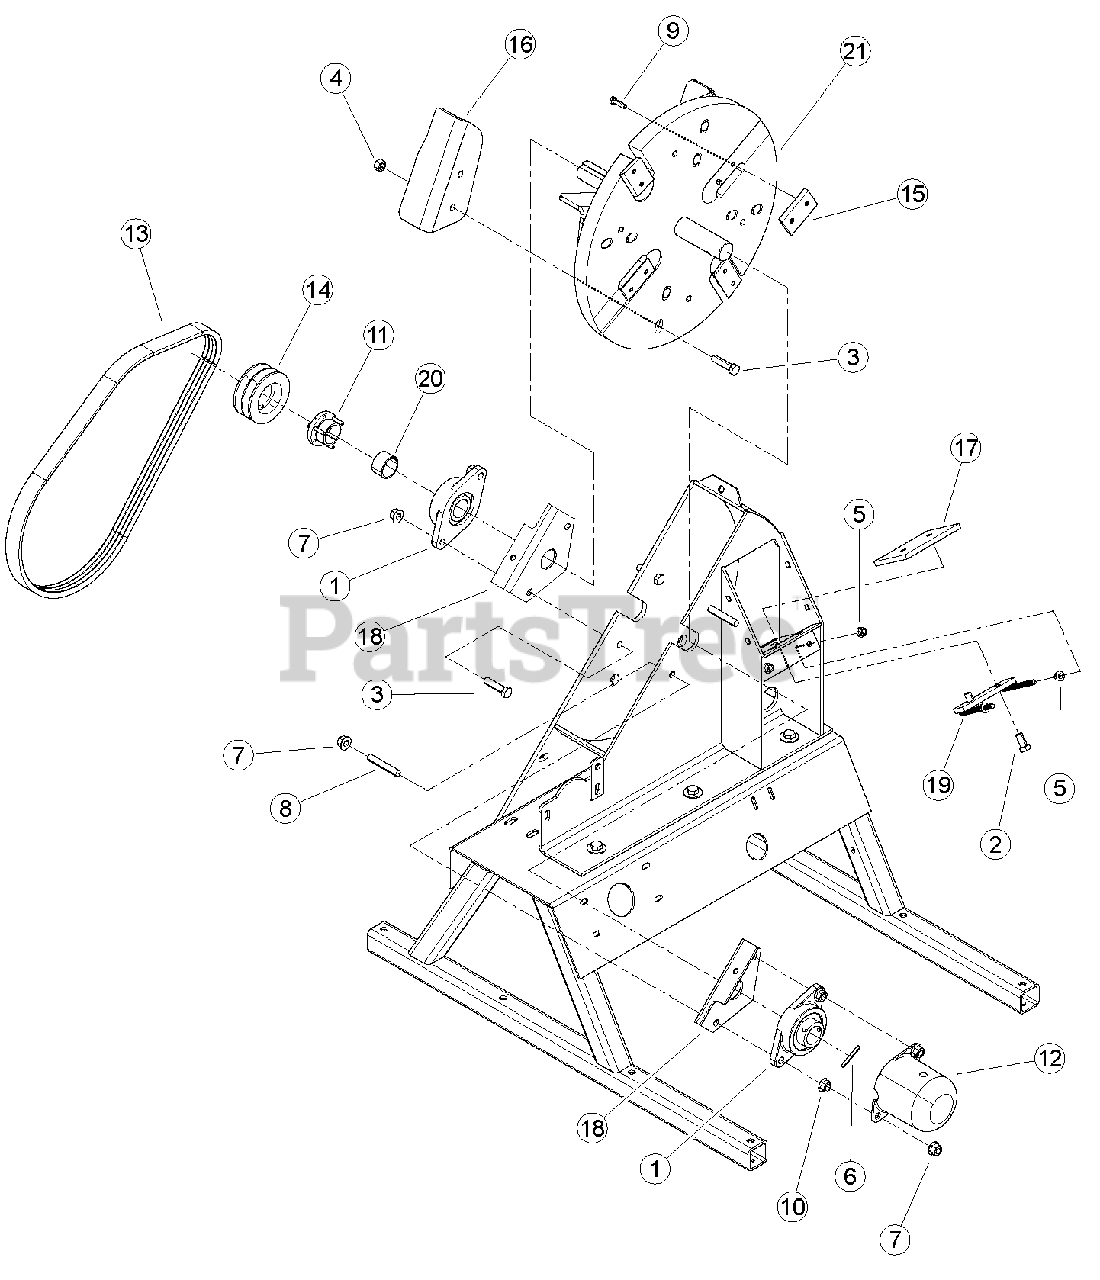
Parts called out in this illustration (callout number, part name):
1	BEARING, 1-1/2" 2-BOLT SET SCREW
2	BOLT, 1/2 X 1 GR5 HEX CAPSCREW ZP
3	BOLT, 1/2 X 2 GR5 HEX CAPSCREW ZP
4	NUT, 1/2" CENTERLOCK GRB ZP
5	NUT, 3/8" SERRATED FLANGE NC ZP
6	SPRINGPIN, 1/4 X 2" LG
7	NUT, 1/2-13 NYLOCK FLANGE
8	STUD, 1/2"-13 X 3"LG B7 ZP
9	BOLT, 5/16 X 1-1/4 HHD GR8 PATCH
10	NUT, 1/2 SPIRAL LOCK NC ZP
11	BUSHING, SH 1-1/2"
12	CAP, LARGE SHAFT
13	BELT, 2RBX56
14	SHEAVE, 2B 3.8 SH
15	BLADE, TWO EDGE TOOL STEEL (FOR SERVICE ORDER KIT 72493)
16	PADDLE, 5" CHIPPER
17	ANVIL, 4 INCH CHIPPER
18	PLATE, BEARING MOUNT
19	WELDMENT, BLOCK ADJUSTOR
20	SPACER, 1-3/4 X 9/16 X .120
21	WELDMENT, 5" CHIPPER DISK
